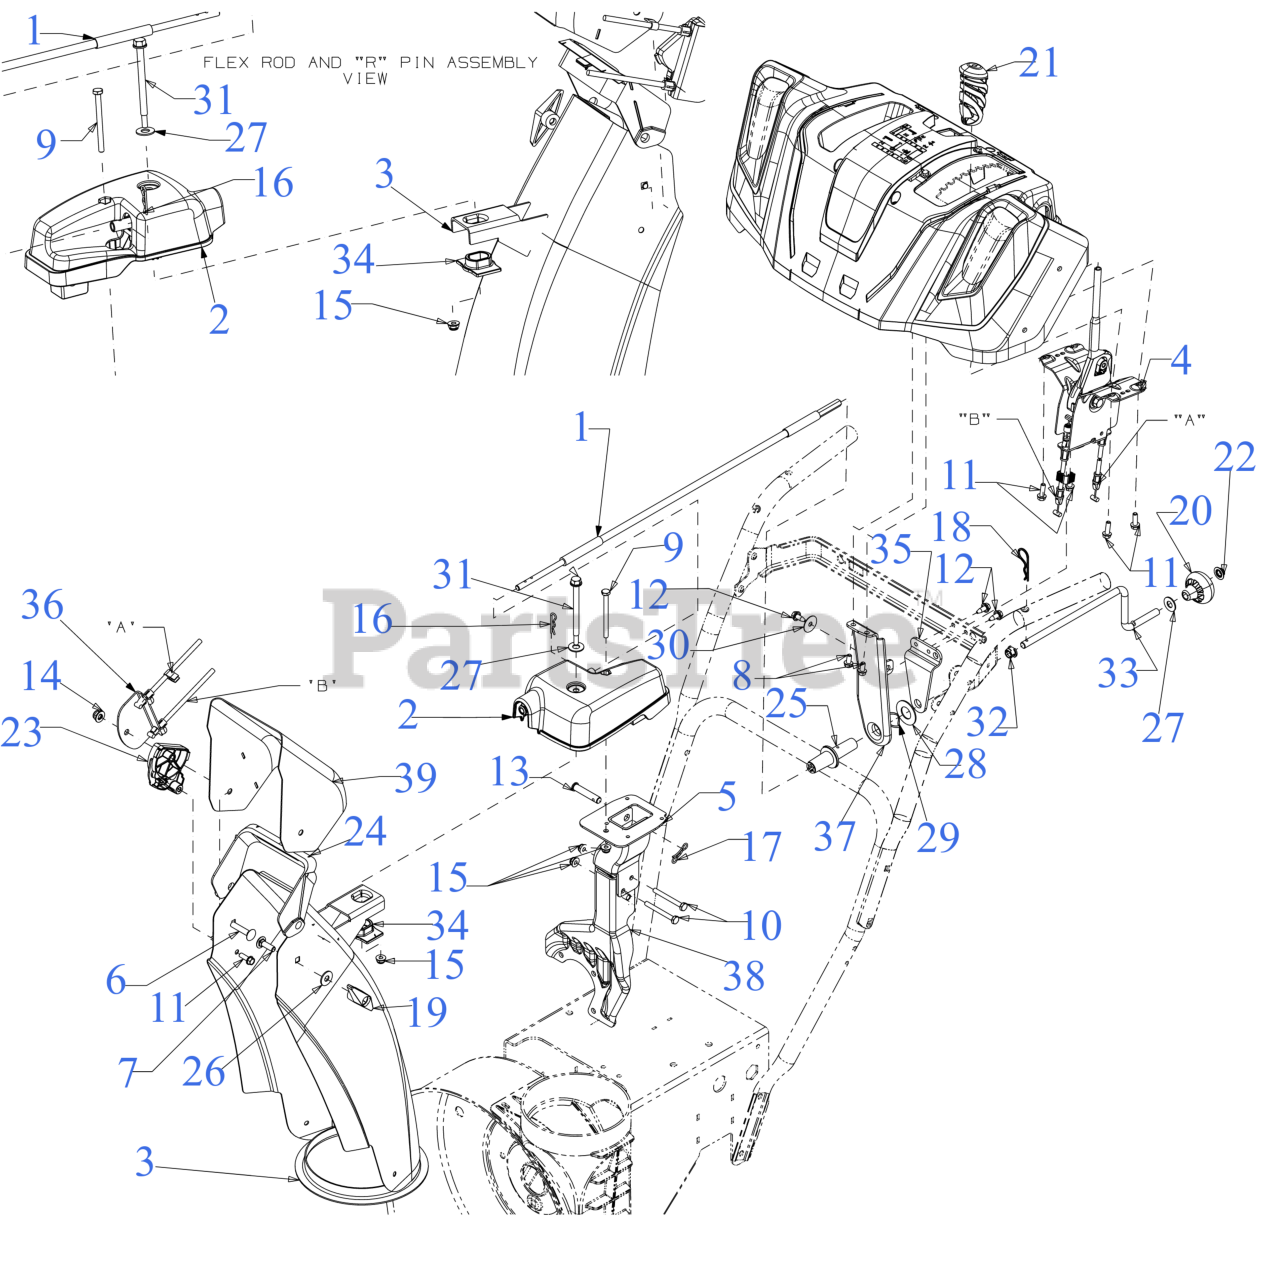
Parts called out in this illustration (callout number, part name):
1	CONTROL ASSEMBLY
2	2-WAY CHUTE ROTATE GEARBOX
3	LOWER STEEL CHUTE 6" DIA
4	2-WAY STEEL CHUTE CONTROL ASSEMBLY
5	EXTENSION CHUTE MAST
6	CARRIAGE BOLT 5/16-18 x 1.50
7	CARRIAGE BOLT 5/16-18 x 1.00
8	HEX SCREW 1/4-15 x .50
9	SCREW 1/4-20 x 3.0 GR5
10	SCREW 1/4-20 x 2.25 GR5
11	SCREW 1/4-15 x .750
12	SCREW 1/4-20X.625
13	CLEVIS PIN 3/8 x 1.87
14	FLANGE LOCK NUT 5/16-18
15	FLANGE LOCK NUT
16	INTERNAL COTTER PIN
17	BOW TIE COTTER PIN 1/4-5/16
18	INTERNAL COTTER PIN
19	WING KNOB NUT
20	SHIFT KNOB
21	PTO HANDLE GRIP .355 ID
23	CHUTE TILT GUIDE
24	UPPER CHUTE ADAPTER
25	CHUTE ROD COUPLER
26	FLAT WASHER
27	FLAT WASHER
28	FLAT WASHER
29	WAVE WASHER .785X1.00X.012
30	FLAT WASHER
31	SHOULDER SCREW
32	BUSHING .380 ID
33	CHUTE CRANK (POWDER BLACK)
34	HELICAL GEAR CHUTE ADAPTER
35	ROD SUPPORT BRACKET
39	UPPER STEEL CHUTE (REMOTE TILT)
